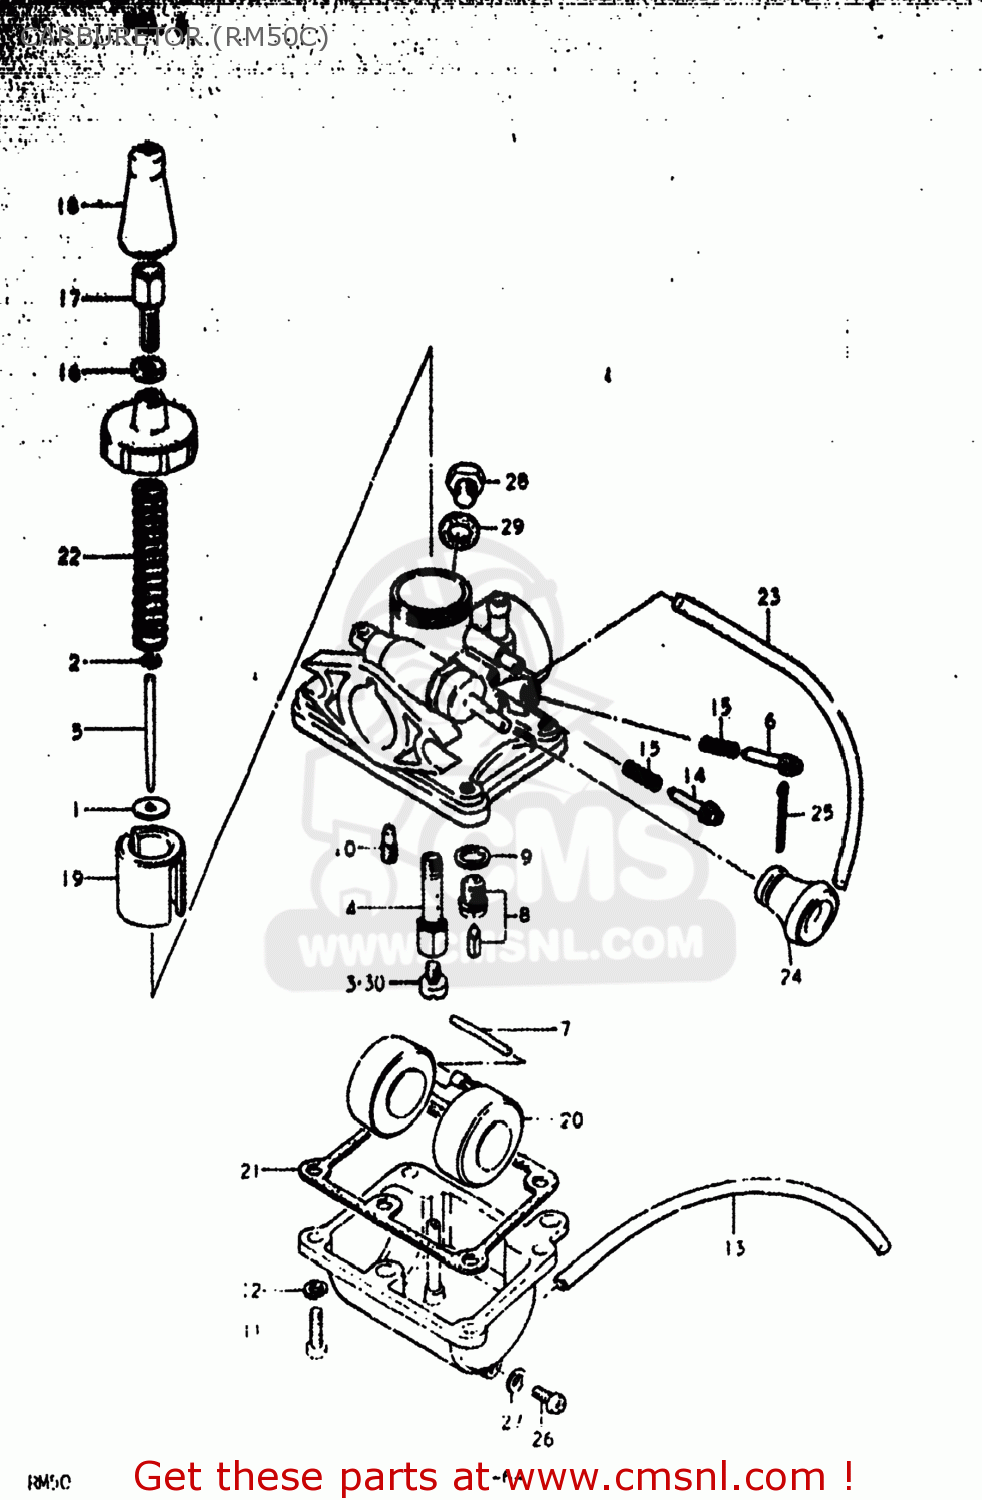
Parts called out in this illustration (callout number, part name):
1	PLATE,THROTTLE VALVE
2	CLIP,NEEDLE
3	JET,MAIN
4	JET,NEEDLE
5	NEEDLE JET
6	SCREW,AIR
7	PIN,FLOAT
8	VALVE ASSEMBLY,NEEDLE
9	GASKET,NEEDLE VALVE (NAS)
10	JET,PILOT
11	SCREW
12	LOCK WASHER
13	HOSE
14	SCREW,THROTTLE STOP
15	SPRING
16	NUT
17	ADJUSTER,CABLE
18	CAP
19	VALVE,THROTTLE
20	FLOAT
21	GASKET,FLOAT CHAMBER (NAS)
22	SPRING,THROTTLE VALVE
23	HOSE
24	LEVER
25	COTTER PIN
26	SCREW
27	GASKET,DRAIN PLUG (NAS)
28	BOLT
29	GASKET,THRO VALVE INSPECTION (NAS)
30	JET
